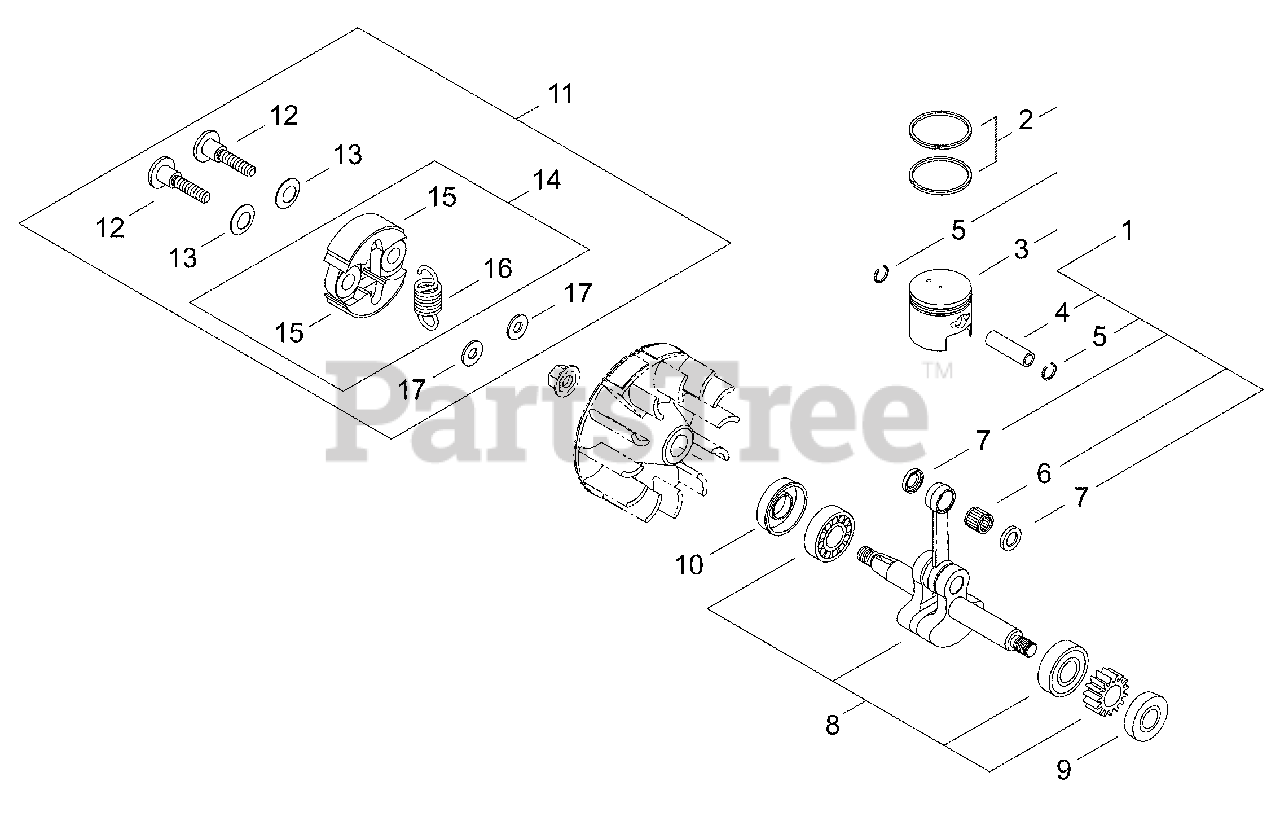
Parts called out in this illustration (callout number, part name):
1	PISTON KIT
2	RING, PISTON
3	PISTON
4	PIN, PISTON
5	RING, RETAINING
6	BEARING, NEEDLE
7	SPACER - 9
8	CRANKSHAFT ASSY
9	SEAL, OIL - 12
10	SEAL, OIL - 12
11	CLUTCH SHOE SET
12	BOLT, CLUTCH
13	WASHER - SPRING
14	CLUTCH ASSY
15	SHOE, CLUTCH
16	SPRING, CLUTCH
17	WASHER - 6
